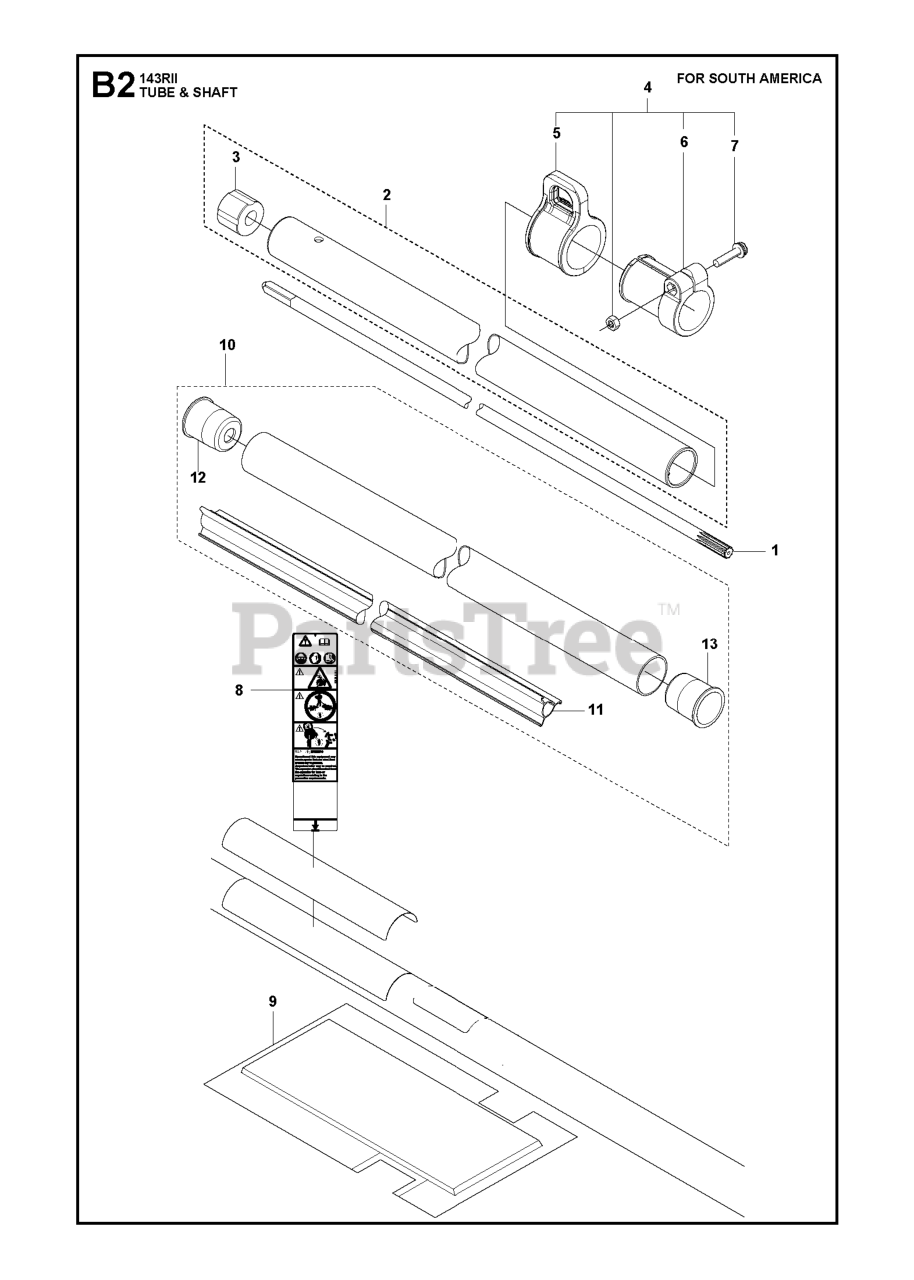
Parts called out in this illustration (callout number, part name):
1	DRIVE SHAFT
2	PIPE COMP.
8	LABEL WARNING TRIMMERS AND BRU
9	PROTECTOR (RPLS 405017110)
12	PLUG
13	PLUG
